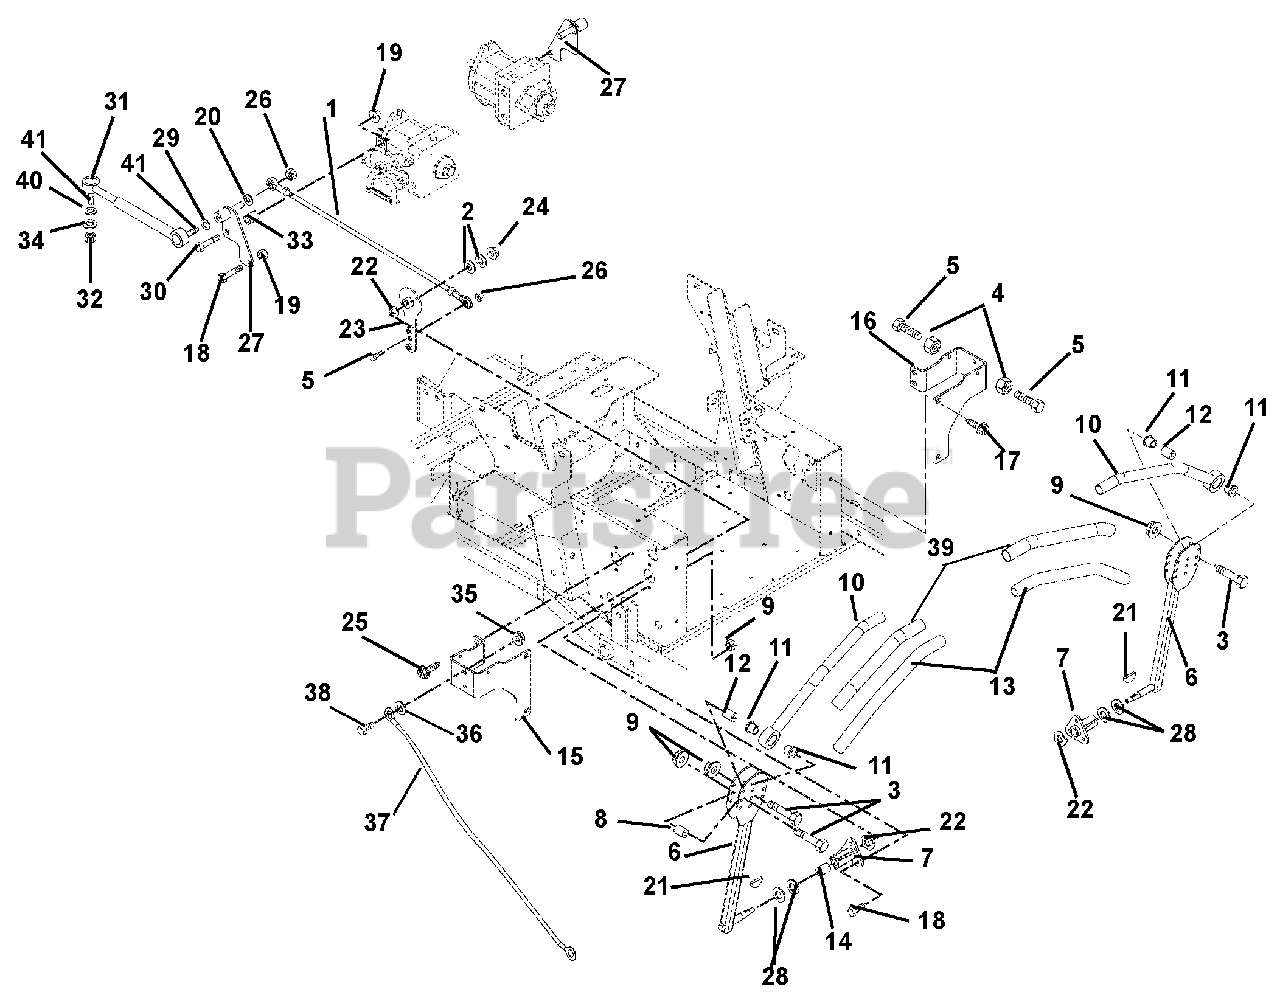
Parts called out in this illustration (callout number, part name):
1	ASSY,STEERING ROD .38RODX21.65
2	@WSHR-FL-STL.406X.812X.065 YWZ
3	@BLT-HEX .31-18X1.75 GR5 YWZC
4	NUT-HEX-JAM .375-16 YWZC
5	BLT-HEX .375-16X1.750 FTD YWZC
6	CONTROL ARM WELDMENT - BLACK
7	BUSHING, FLANGE
8	BSHG, ECCENTRIC .328X.750X.970
9	@NUT-LK-TOP-FLG .31-18 YWZC
10	HANDLE WLDMT LH
11	BSHG-FLG .762X1.48X.44 NYL
12	SPACER .328 X .76 X 1.01
13	GRIP, HANDLEBAR 1.00X1.38X11.3
14	BSHG .625X.750X.500
15	STOP, STEERING - RH
16	STOP, STEERING - LH
17	@SCR-TAP .38-16X.75 HWH TR YWZ
18	@BLT-HEX .31-18X.75 GR5 YWZC
19	@NUT-LK-TOP-FLG .31-18 YWZC
20	@WSHR-LK .38X.094 REG YWZC
21	KEY-WDRF .13X.63 HRD#5
22	WAVE WASHER .640X.875X.125FH
23	WMT-PIVOT ARM
24	@NUT-LK-TOP-FLG .38-16 YWZC
25	@SCR-TAP .38-16X.50 HWH TR YWZ
26	@NUT-LK-CTR-JAM .375-16 YWZC
27	WMT-RTN/DAMPER/ROD END
28	WSHR-FL-STL .630X1.005X.062 YZ
29	@WSHR-LK .31X.078 REG YWZC
30	@BLT-HEX .31-18X1.25 GR5 YWZC
31	DAMPER, STABILUS
32	@NUT-LK-TOP-FLG .31-18 YWZC
33	SPACER .318X.430X.375
34	@WSHR-FL-STL.38X.875X.083 YWZC
35	@NUT-LK-TOP-FLG .25-20 YWZC
36	WSHR-FL-STL .265X.50X.087YWZC
37	CABLE, SEAT PROP.
38	@BLT-HEX .25-20X.75 GR5 YWZC
39	TUBE, .88ID X 1.00OD X 10.25
40	WSHR-FL-STL .328X1.0X.094 YWZC
41	STUD-BALL-THREADED
